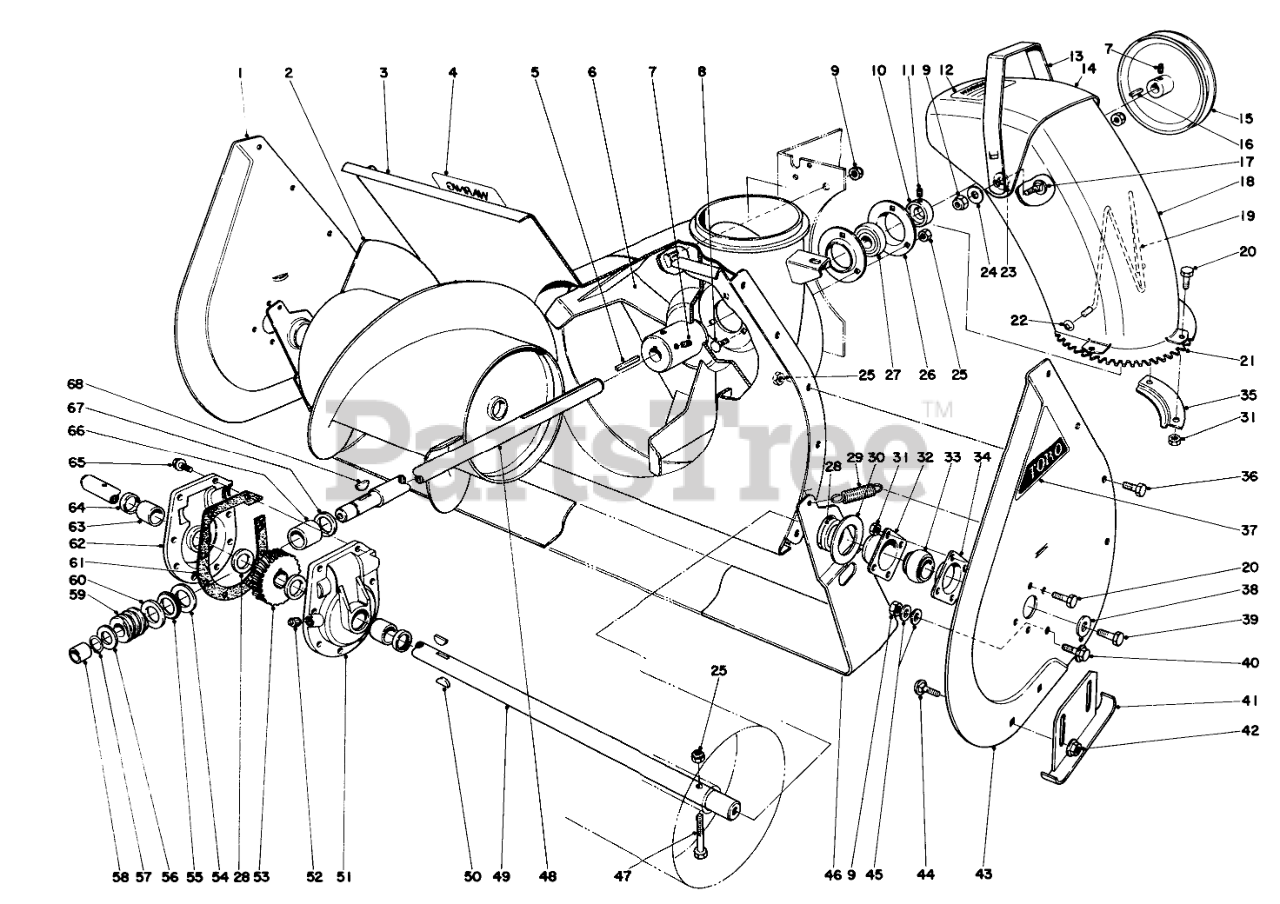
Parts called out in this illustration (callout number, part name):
1	Side Plate Right
2	Auger R.H.
3	Auger Housing
4	Decal
6	IMPELLER WA RO
7	SCREW-SET, SQH
8	BOLT-CARR
9	NUT-LOCK, CONE
10	EXT LOCKING COLLAR
11	SCREW-HSH
12	Decal
13	DEFLECTOR HANDLE B
14	Chute Deflector
15	IMPELLER PULLEY
16	SQUARE KEY
17	SCREW-CARR
18	Chute
19	WIRE-CHUTE
20	SCREW-HH
21	Chute Swivel Gear
22	NUT-PUSH
23	WASHER-RUBBER
24	WASHER-BELLEVILLE
25	NUT-LOCK, CONE
26	BRG FLANGE
27	BALL BRG W/COLLAR
28	WASHER-THRUST
29	SPRING-TENSION
30	SCRAPER BLADE SPACER
31	NUT-LOCK, CONE
32	BEARING-FLANGE, FRONT
33	BEARING
34	BEARING-FLANGE, REAR
35	CHUTE RETAINER
36	SCREW-HH
37	AUGER SIDE PLT DECAL
38	WASHER
39	SCREW-HH
40	SCREW-HHF
41	Skid
42	NUT-HHF, WHIZ
43	Sideplate Auger Left
44	SCREW-CARR
45	WASHER-FLAT
46	24 SCRAPER BLD
47	Auger Bolt
48	Impeller Shaft
49	24 AUGER SHAFT
50	KEY-WOODRUFF
51	Gear Case L.H. (Incl. Ref. 63-64)
52	PLUG-PIPE, SQH
53	GEAR-WORM, 27T
54	WASHER-THRUST
55	BEARING-THRUST
56	WASHER-THRUST
57	Ring-Snap
58	BUSHING
60	THRUST-WASHER
61	Gasket
62	Gear Case R.H. (Incl. Ref. 63-64)
63	BUSHING
64	SEAL-OIL
65	SCREW-HWHTF
66	BUSHING-SPECIAL
67	RING-QUAD
68	KEY-WOODRUFF
